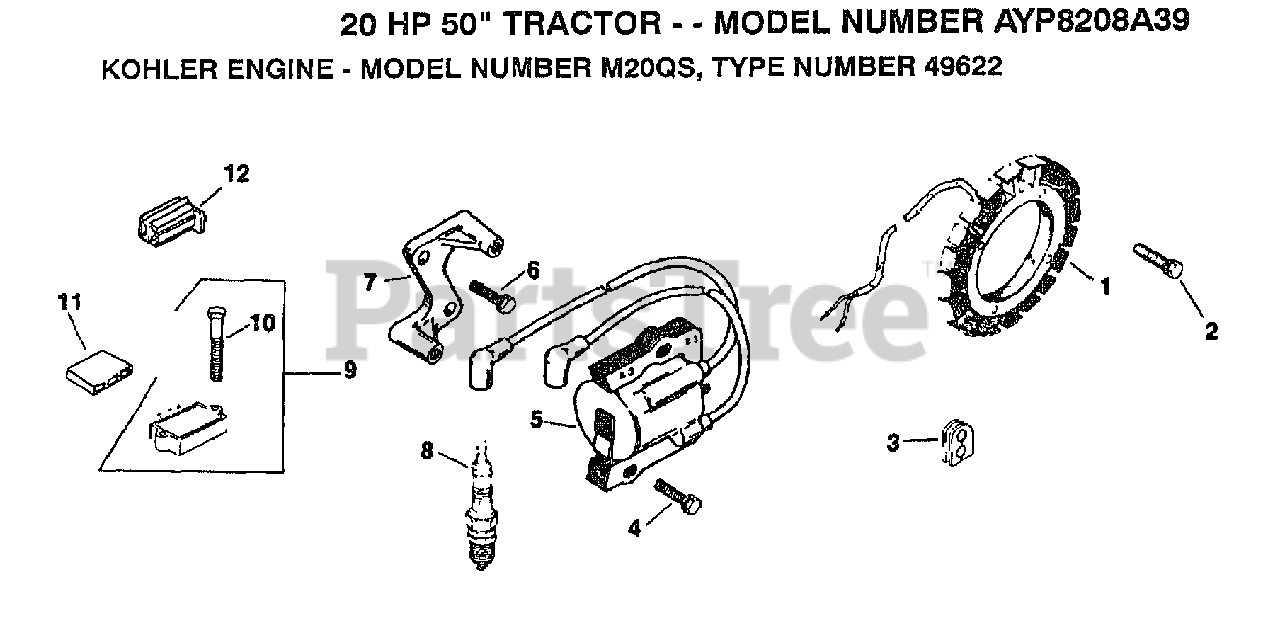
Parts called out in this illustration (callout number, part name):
1	KIT
2	SCREW
5	MODULE, IGNITION
7	BRACKET, MODULE
9	KIT, RECTIFIER-REGULATOR
10	SCREW
11	CONNECTOR
12	CONNECTOR
